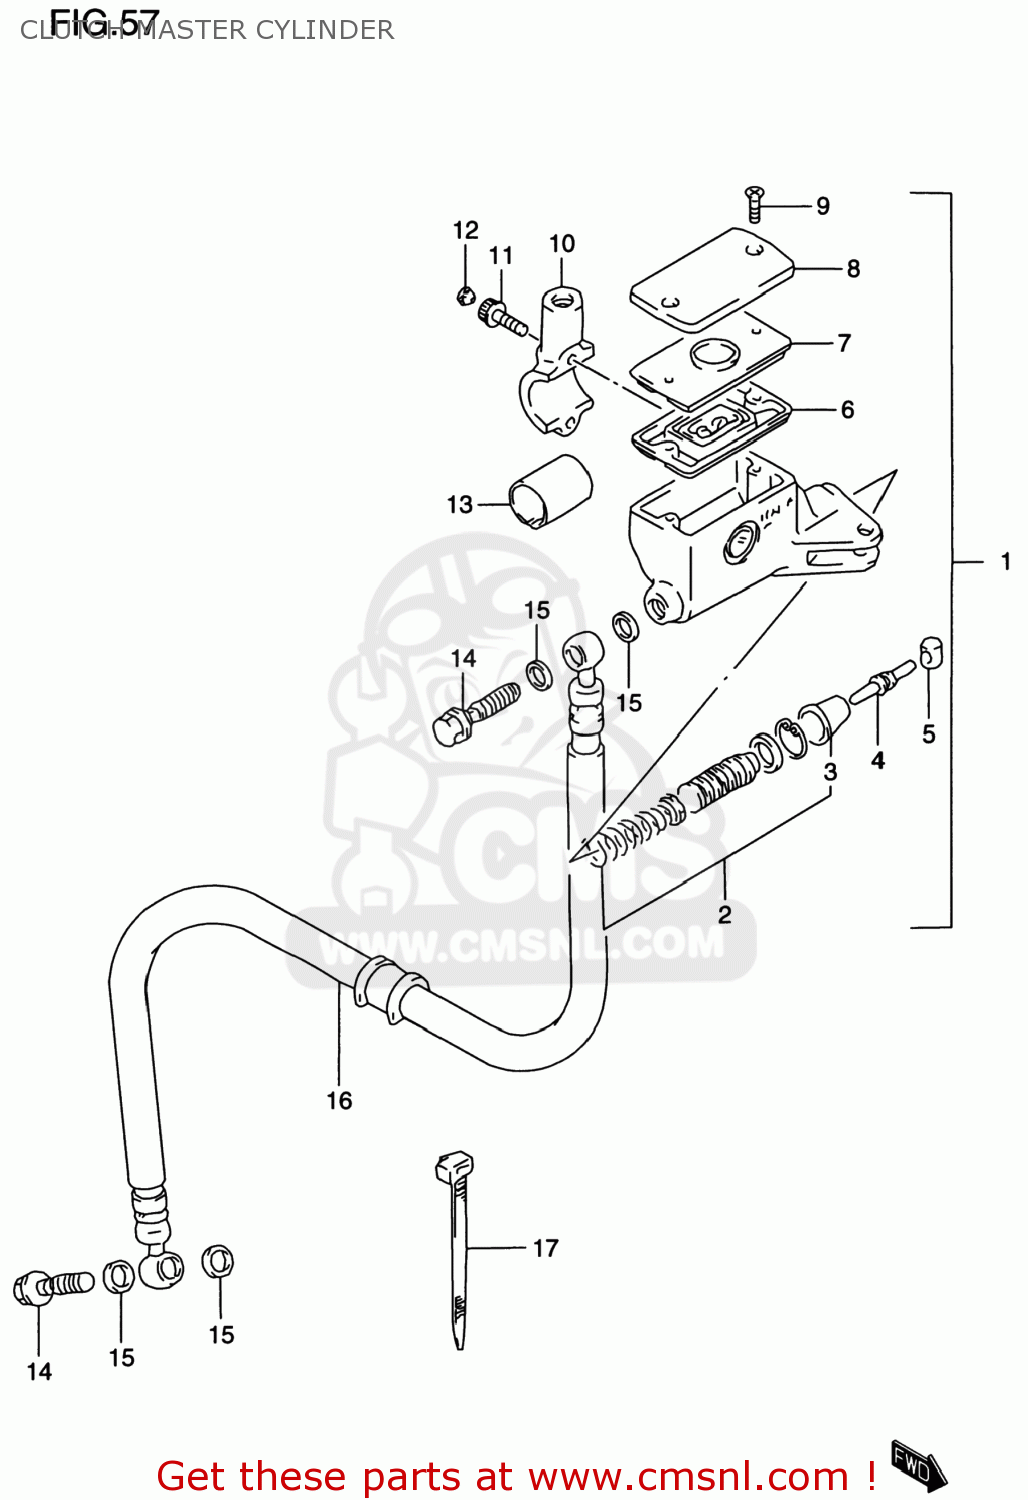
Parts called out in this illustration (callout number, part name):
1	CYLINDER ASSEMBLY,CLUTCH MASTER
2	PISTON & CUP SET
3	BOOT
4	PUSH ROD
5	BUSH
6	7
7	PLATE,DIAPHRAGM
8	CAP
9	SCREW
10	HOLDER
11	BOLT,CRKCASE,R
12	CAP(OD:10)
13	SPACER,CLUTCH MASTER CYLINDER
14	BOLT UNION
15	WASHER(10X15X1.5)
16	HOSE,CLUTCH
17	CLAMP(L:125)
